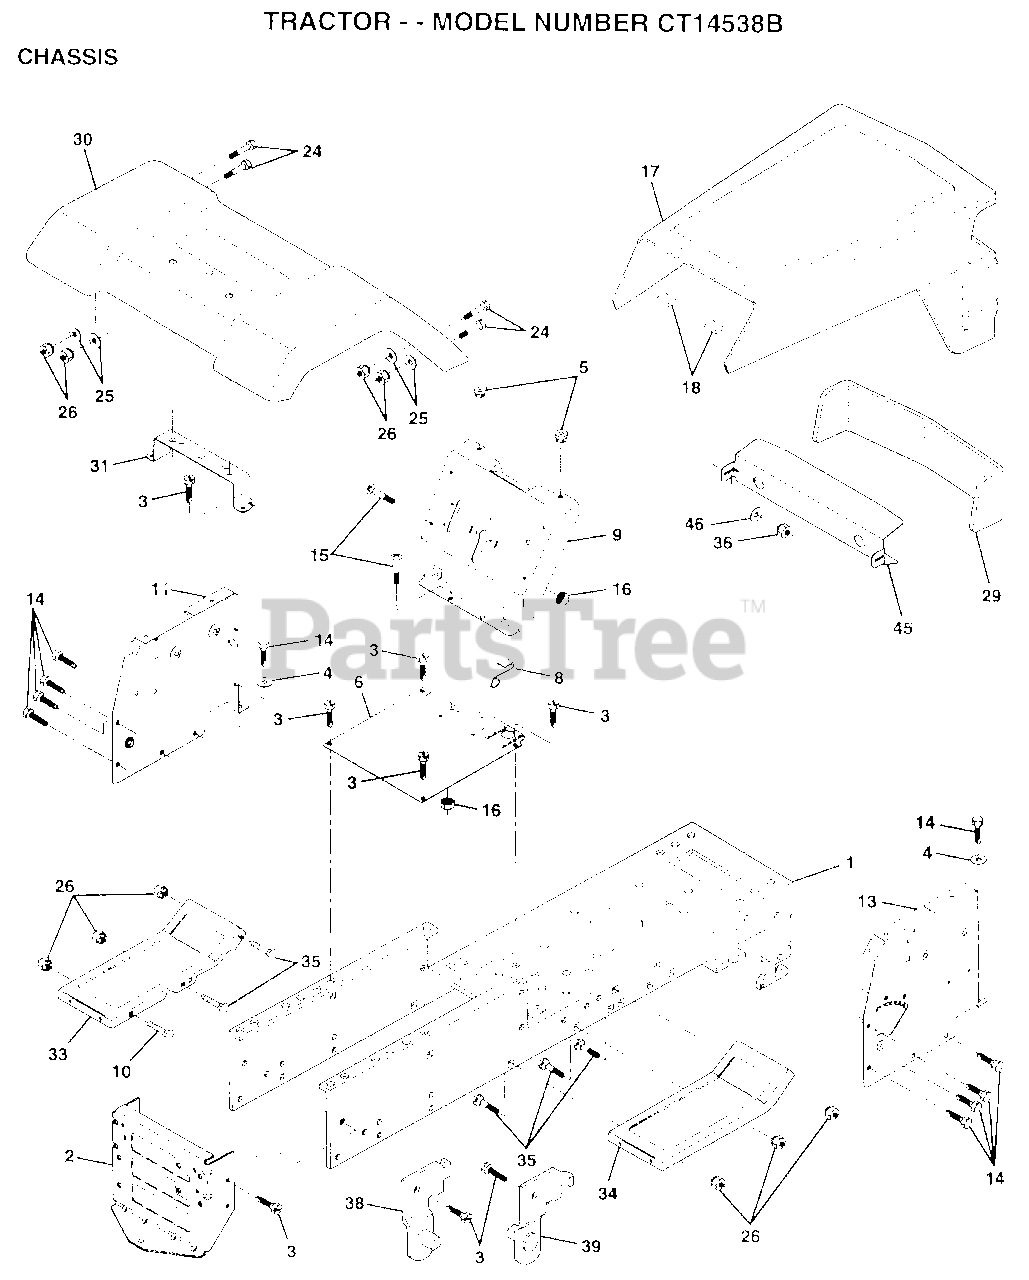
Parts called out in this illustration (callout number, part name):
1	CHASSIS.WLD.11GA
3	SCREW
4	WASHER
8	"CLIP,INSULATOR"
9	DASH.SLKSC.LT.1PC
11	PANEL.DASH.LH.
14	SCREW LT
15	SCREW
17	HOOD/GRILL ASM
24	BOLT
25	WASHER
26	NUT
29	LENS SERVICE KIT
30	FENDER
31	BRKT FENDER
33	FOOTREST LH
34	FOOTREST RH
35	BOLT
36	PAL NUT LT
38	BRACKET ASM LH
39	BRACKET ASM RH
46	RETAINER
